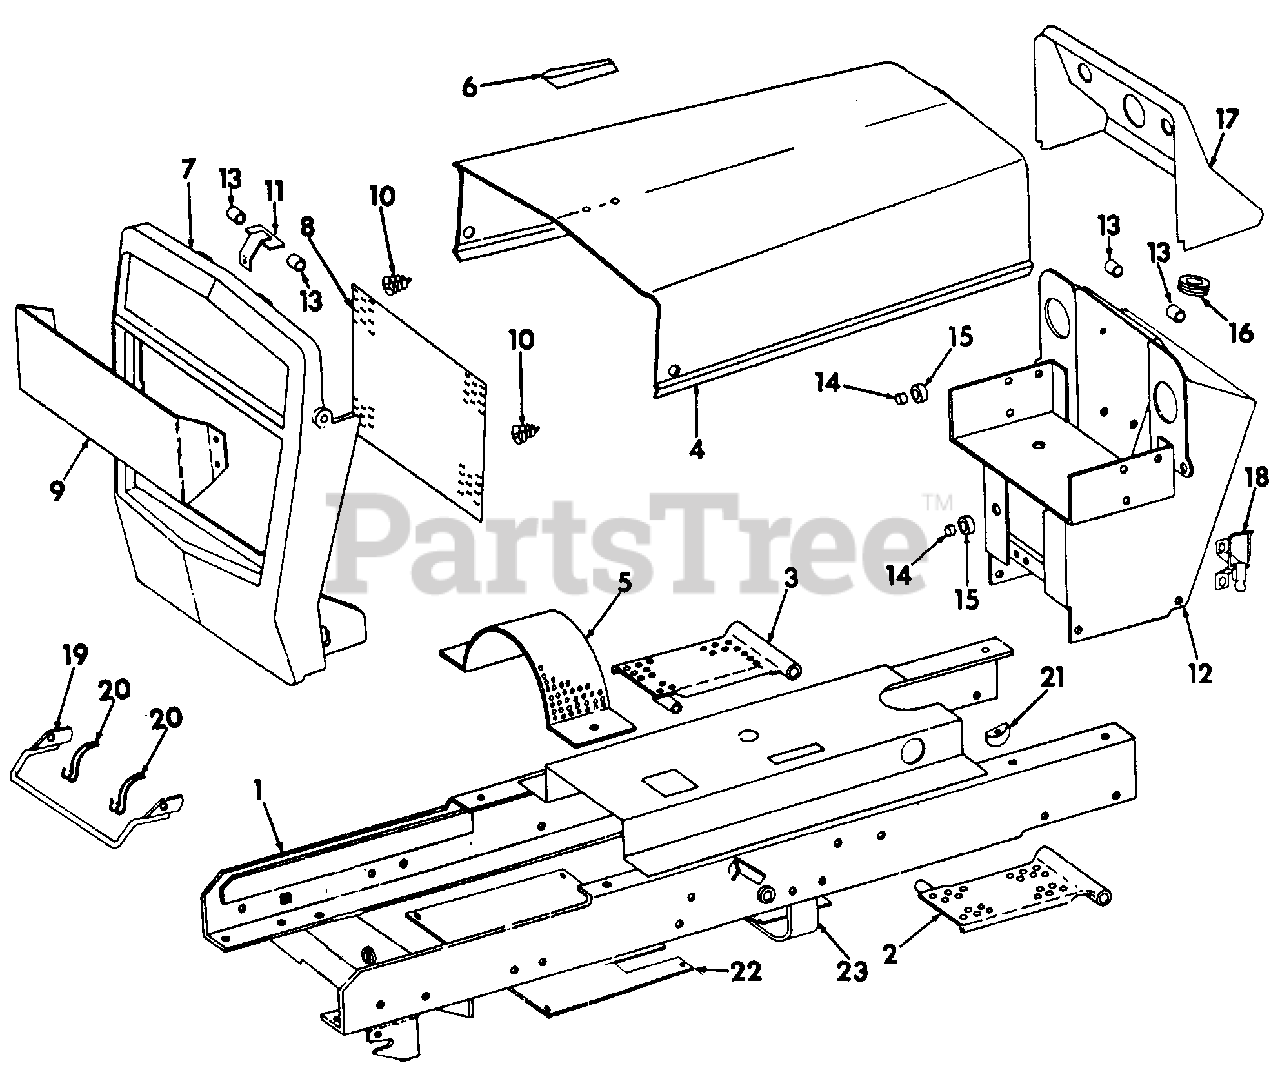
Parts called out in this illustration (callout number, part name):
1	Frame Assy
2	Support Assy, Foot LH
3	Support Assy, Foot RH
4	Hood Assy
5	Shield, Clutch
6	Product Graphic, Hood Ornament
7	Housing, Grille
9	Strip, Panel
10	Spring, Hold Down
11	Bracket Assy, Front Hood
12	Pedestal Assy
13	Pad, Hood Bumper
14	Spacer, Hood Roller Lock
15	Roller, Hood Lock, Rubber
16	Grommet, Instrument Panel
17	Panel, Instrument
18	Latch Assy, Hood
19	Hitch Assy, Quick
20	Spring, Latch
21	Plate, Neutral Adj Cover
22	Sheet, Bottom Clutch Shield
23	Guard Assy, Suction Tube
